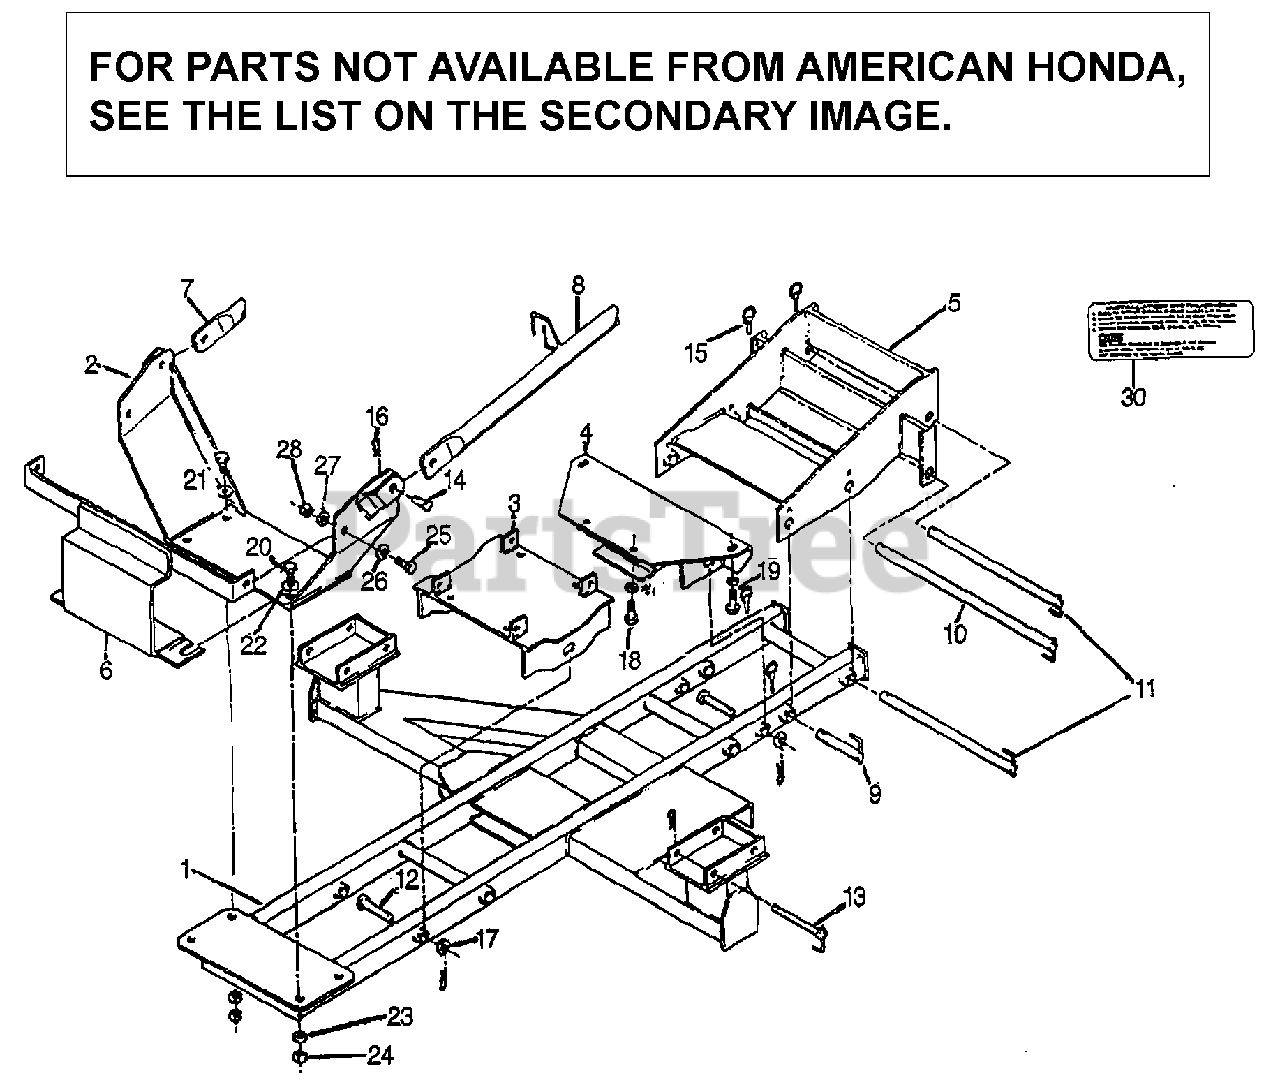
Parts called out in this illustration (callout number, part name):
14	PIN, CLEVIS (5/8X1 1/4")
15	PIN, LYNCH (7/16")
16	PIN, CLIP (#11)
17	BUSHING (1 1/4X3/4")
